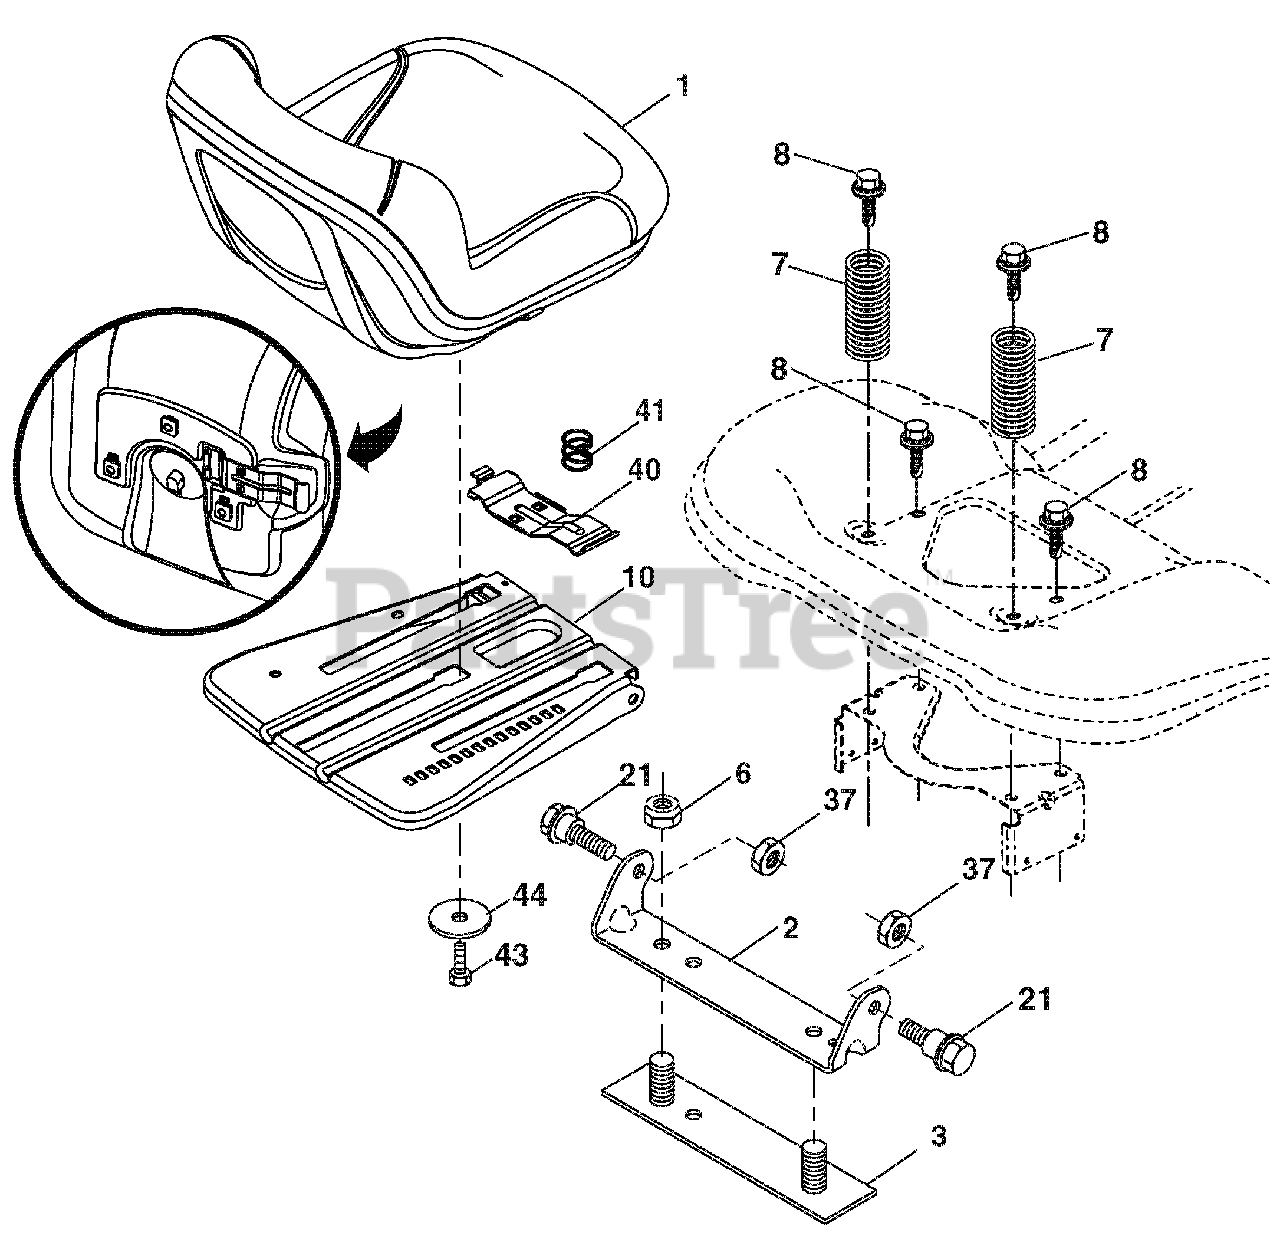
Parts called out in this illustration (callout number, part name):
1	SEAT.TA150.KB/SLD.BLK.ARIENS
2	BRACKET.PIVOT.FENDER.2002
3	STRAP ASM.FENDER.94
6	Locknut, Washer Insert 3/8-16
7	SPRING.SEAT.CPRSN.2.250.BLK.ZI
8	BOLT.5/16-18UNCX3/4 W/SEMS.BLK
10	PAN ASM.SEAT.3PT.
21	BOLT.SHLD.5/16-18 UNC-2A.BLK D
37	Locknut, Washer Insert 5/16-18
40	HANDLE.SLIDE.SEAT.TEX.MILSCO
41	SPRING.LATCH.SEAT.TEX
43	BOLT.FIN.HEX.3/8-16UNC X 3/4
44	WASHER.13/32 X 2 3/8 X 12GA.
